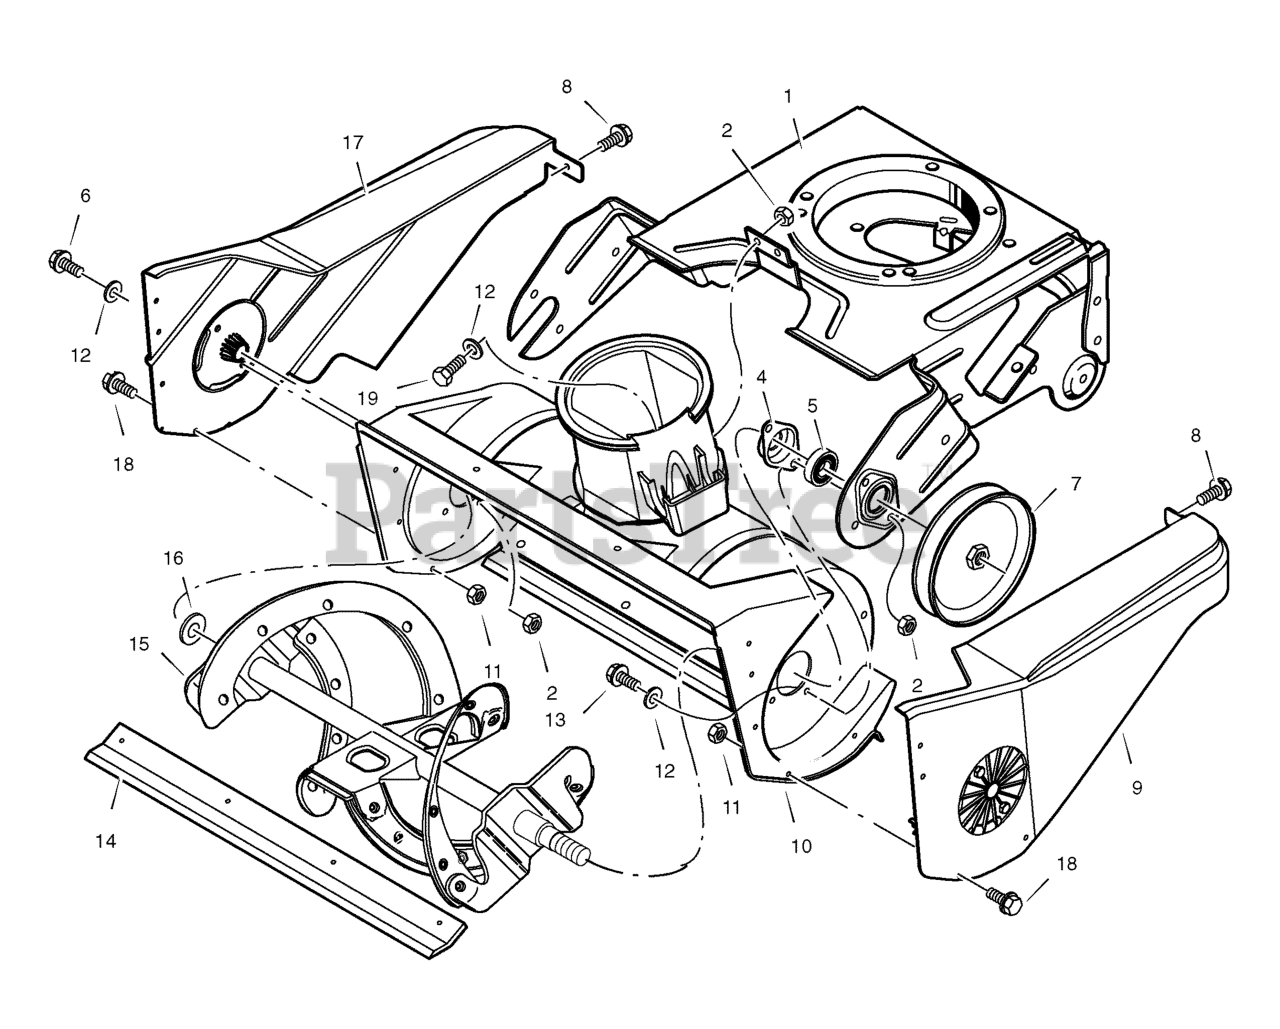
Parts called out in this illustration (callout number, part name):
1	Frame, Motor Box
4	Retainer, Bearing
5	Bearing
7	Pulley, Auger
9	Cover, Left Belt
10	Assembly, Auger Housing
11	Nut
12	Washer
14	Blade, Scraper
15	Auger Assembly
17	Cover, Right
